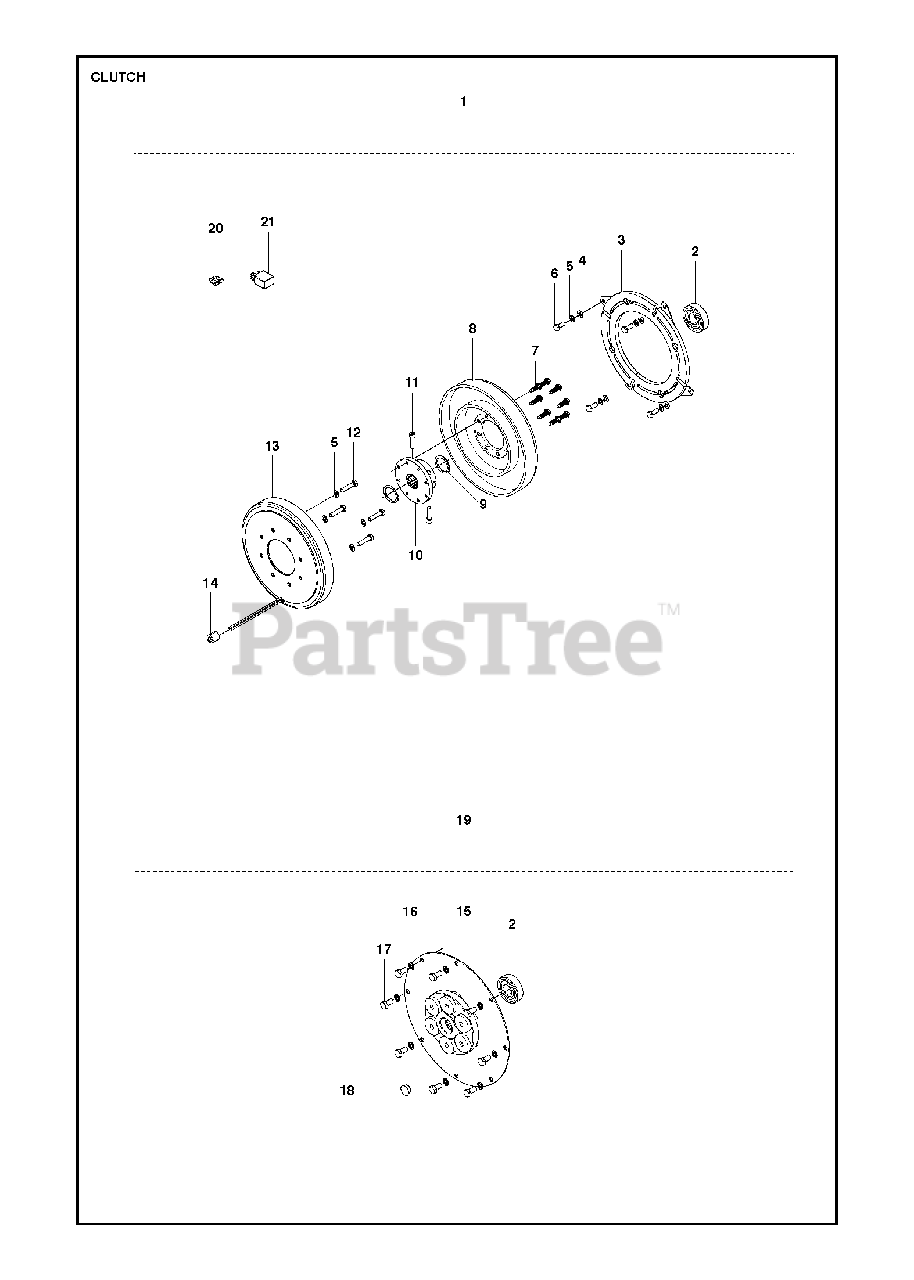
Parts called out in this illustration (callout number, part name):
4	WASHER1
5	SPRING WASHER1
11	SCREW IHSCM1
17	SCREW EHHM19
